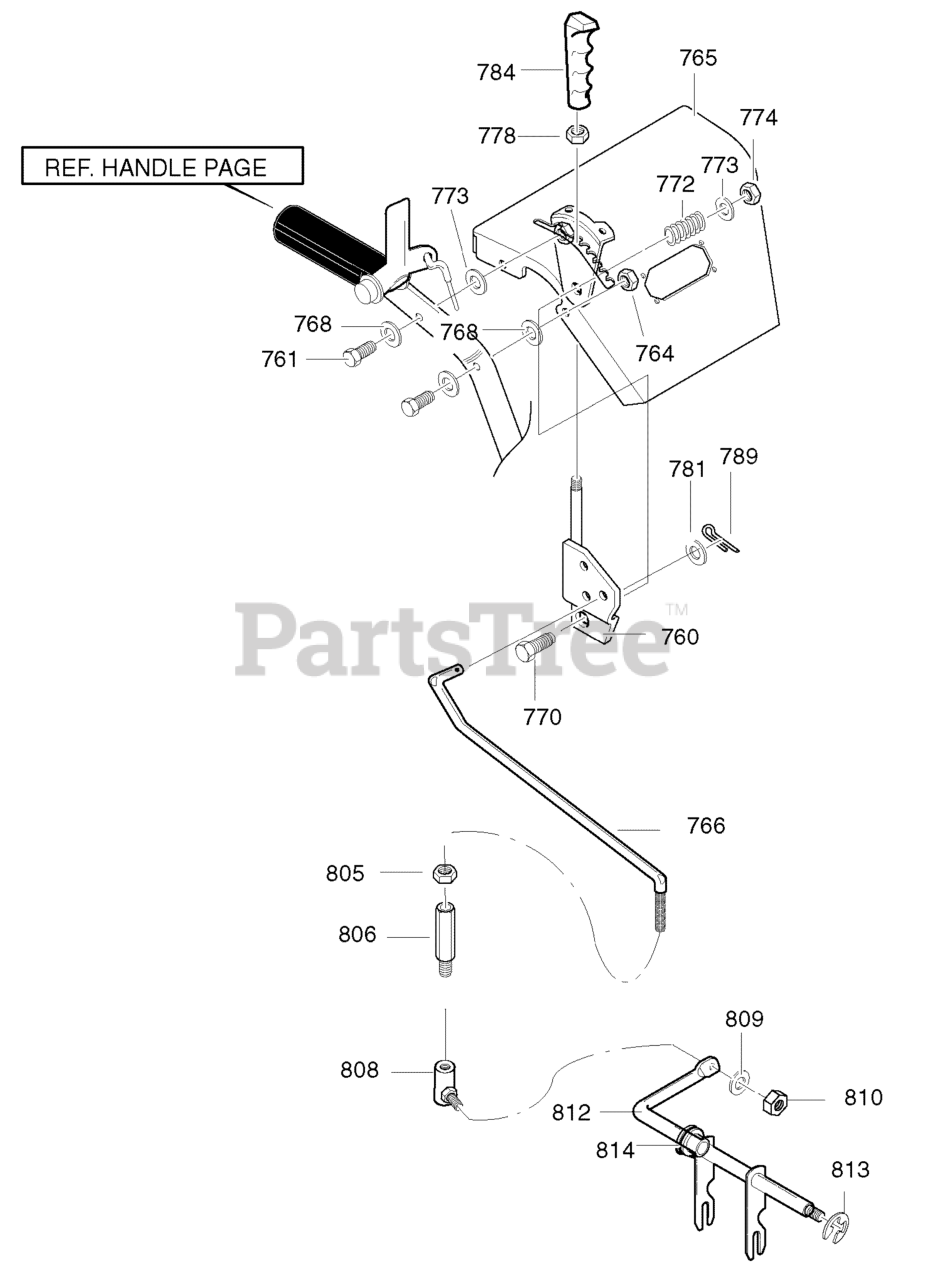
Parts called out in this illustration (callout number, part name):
760	HANDLE ASSY SPD CTRL
761	SCREW, 5/16-18 X 1.75
764	NUT, 5/16-18
765	ASSY. BAY PANEL - LT
766	ROD, SPEED CONTROL
768	WASHER
770	SCREW 3/8-16X2.00
772	SPRING
773	FLATWASHER
774	NUT, 3/8-16
778	NUT, 3/8-16
781	FLATWASHER
784	GRIP, HANDLE
789	PIN, COTTER
805	NUT, 5/16-18
806	ADAPTER, SPEED ROD -YZ
808	BALLJOINT, STEEL -YZ
809	WASHER
810	NUT, 5/16-18
812	ROD, ASSY YOKE
813	RING, RETAINER
814	BEARING, FLANGE
